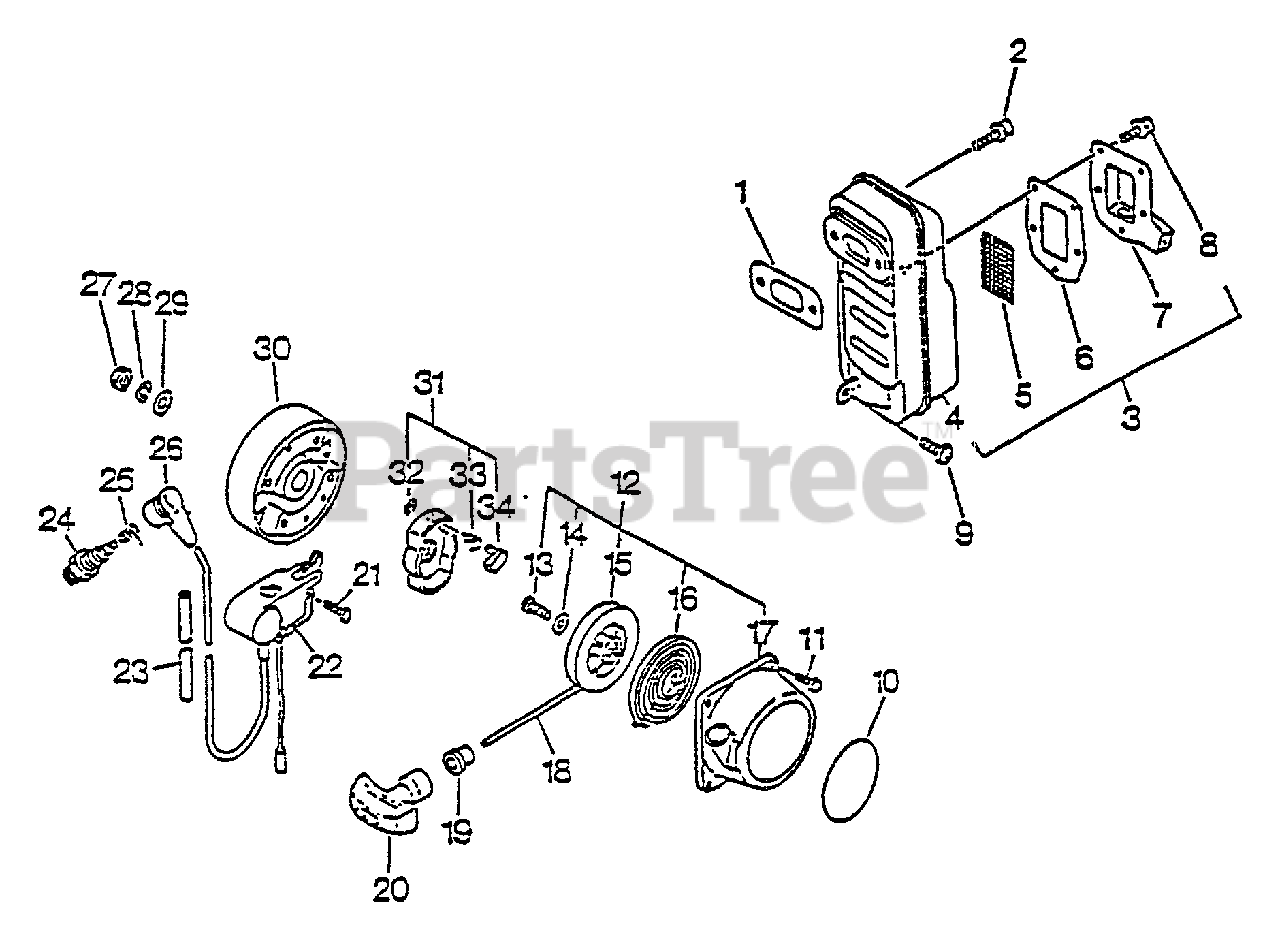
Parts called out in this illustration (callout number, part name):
1	GASKET, EXHAUST
2	SCREW - 6X20
3	MUFFLER ASSY
4	MUFFLER
5	SCREEN, SPARK ARRESTOR
6	GASKET, EXHAUST
7	ADAPTOR
8	SCREW - 4X10
9	SCREW - 5X20
10	LABEL - LESCO
11	SCREW - 4X18
12	STARTER ASSY
14	WASHER
15	REEL, ROPE
16	SPRING, REWIND
17	CASE, STARTER
18	ROPE, STARTER - 4X1110
19	GUIDE, ROPE
20	GRIP, STARTER
21	SCREW - 5X20
22	COIL, IGNITION
23	TUBE - VINYL
24	SPARK PLUG -- BPM-7A
25	TERMINAL, SPARK PLUG CAP
26	CAP, SPARK PLUG
27	NUT - 10
28	LOCKWASHER - 10
29	WASHER - 10
30	FLYWHEEL
31	STARTER PAWL ASSY
32	RING, RETAINING - 4
33	SPRING, RETURN
34	PAWL, STARTER
